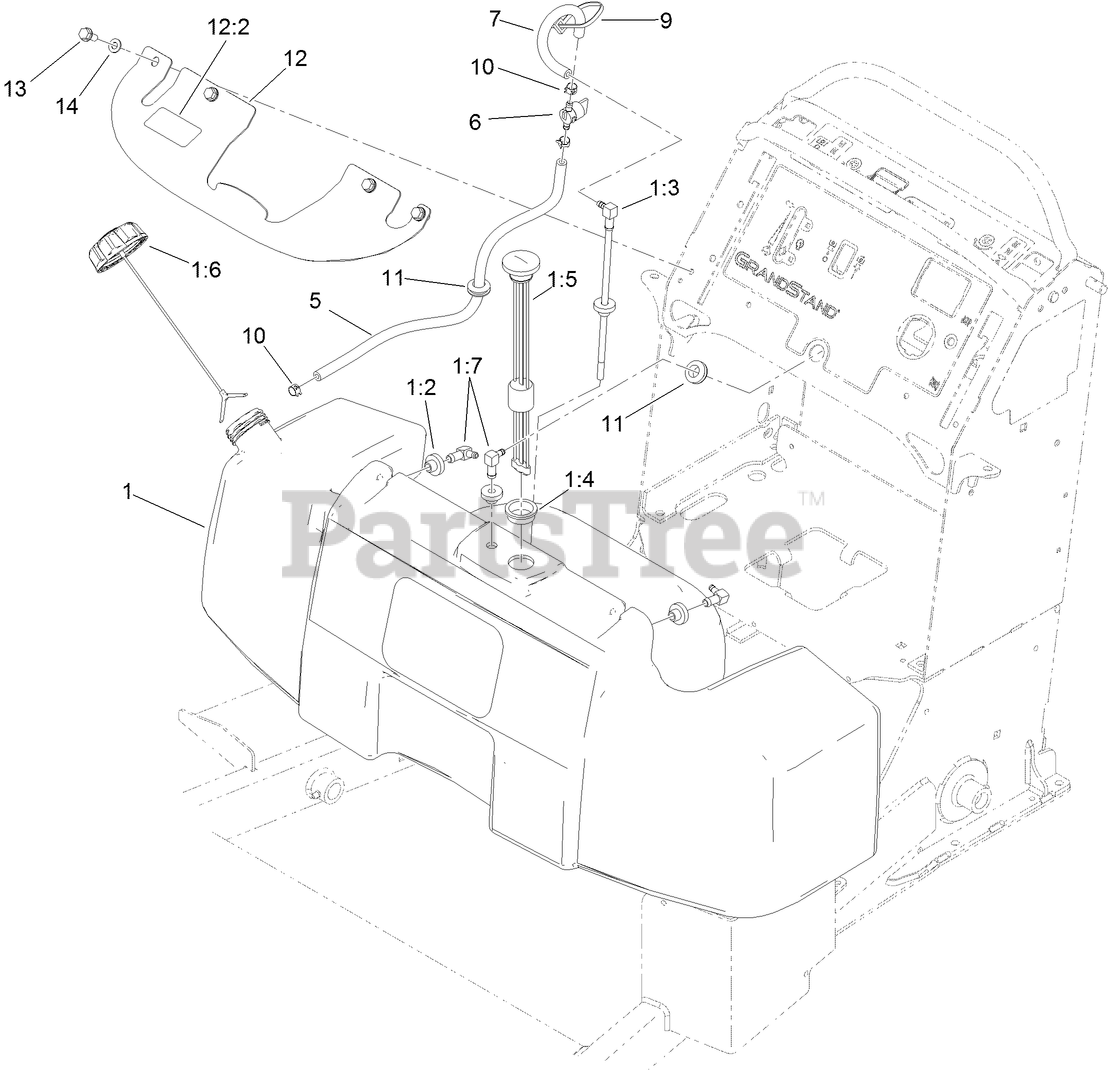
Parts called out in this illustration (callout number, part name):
1	TANK ASM
1:2	BUSHING
1:3	FITTING-FUEL, SCREEN TUBE
1:4	GROMMET
1:5	GUAGE-FUEL
1:6	CAP-FUEL, RATCHETING
1:7	ELBOW-90 DEG
5	HOSE-FUEL
6	VALVE-FUEL
7	HOSE-FUEL
9	TIE-CABLE
10	CLAMP-HOSE
11	GROMMET
12	BRACKET-TANK
12:2	DECAL-FILL, FUEL
13	SCREW-HWHTF
14	WASHER-FLAT
